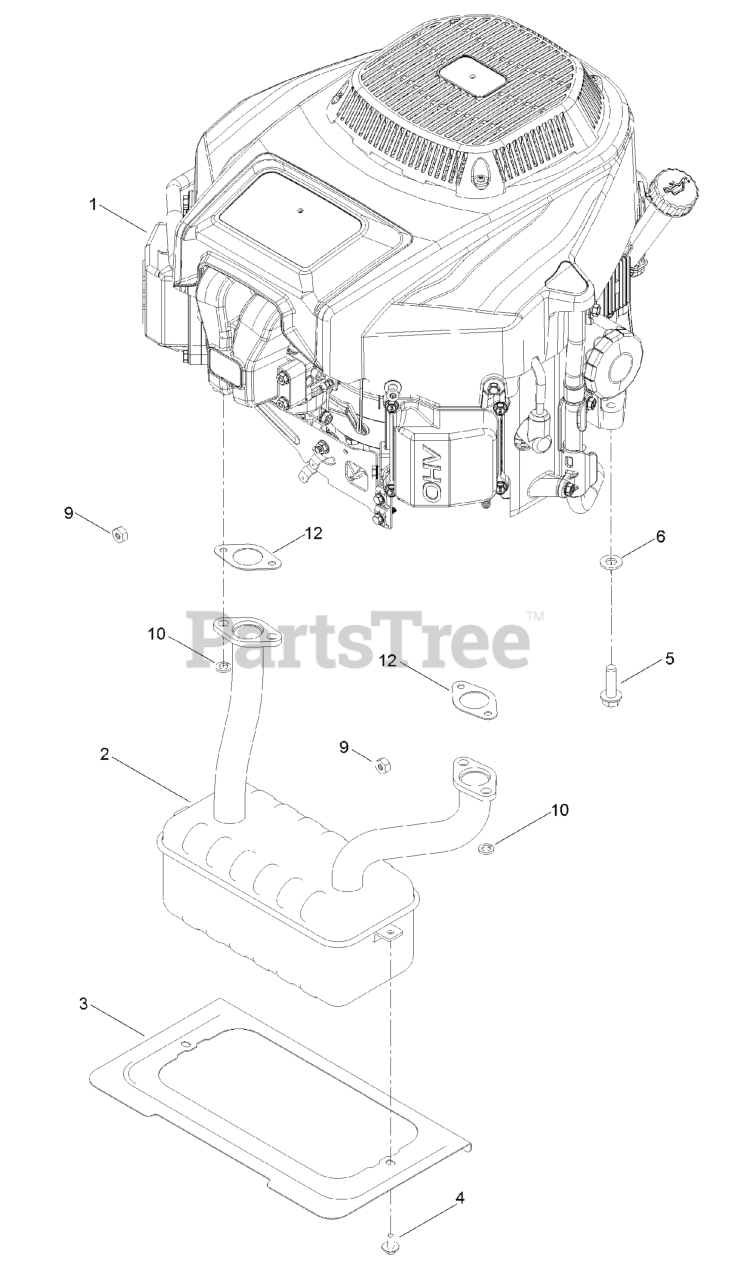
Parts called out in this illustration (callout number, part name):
1	Engine-2P77F
2	MUFFLER
3	SHIELD-HEAT
4	SCREW-HHFTF
5	SCREW-THD
6	WASHER-FLAT
10	WASHER-LOCK, SPLIT
12	GASKET-EXHAUST
